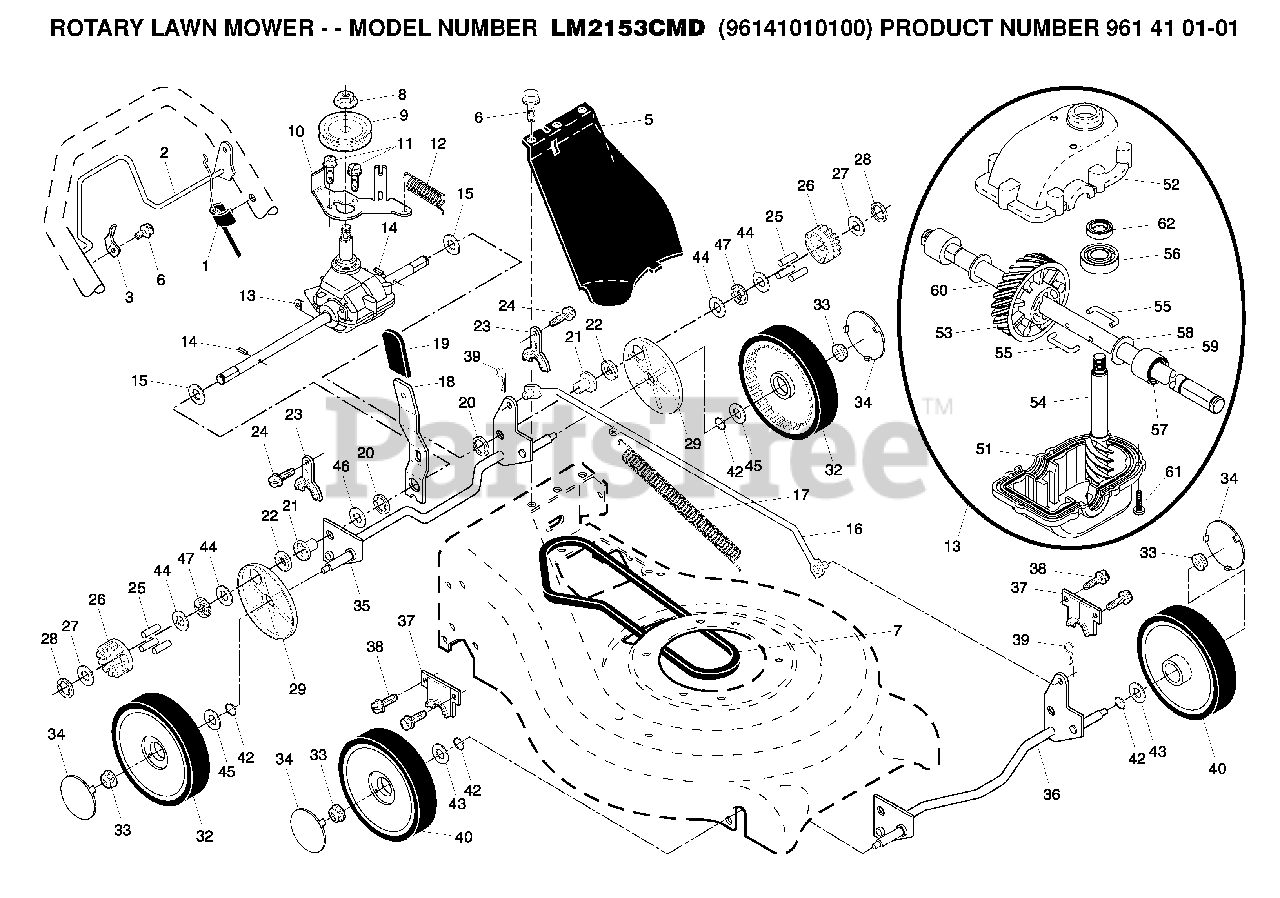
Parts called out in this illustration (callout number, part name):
1	DRIVE CABLE
2	BAIL.CONT.DR.21.RWGD.BLACK
3	DOWNSTOP BRACKET
8	FLANGED LOCKNUT 3/8-16 ZINC
13	TRANSMISSION
14	PIN.SPRING.THRUST
15	THRUST WASHER
16	ROD CONNECTING
17	SPRING
18	SPRING.SELECTOR.SPT.21
19	KNOB, SELECTOR SPRING
21	RP BEARING SUPPORT
22	BEARING, BALL
23	BRACKET
26	DRIVE PINION
27	WASHER
28	E-RING 7/16 RE
29	COVER.DUST.WHEEL
32	WHEEL 9X2
33	HEX FLANGE LOCKNT
34	HUBCAP
35	SHAFT.ASM.REAR.TORQUE
36	SHAFT ASSY FRONT
37	RETAINER.FRONT.SHAFT
39	RETAINER CLIP
40	FRONT.WHEEL.8X2
42	O-RING
43	WASHER PM
44	BELLEVILLE WASHER
45	WASHER FLUT
51	CASE, LOWER
52	GEARCASE.HOUSING
53	GEAR.24.TOOTH.WALK.MOWER
54	SHAFT INPUT
55	WIRE, FORMED
57	SEAL.OUTPUT.SHAFT
62	SEAL INPUT SHAFT
